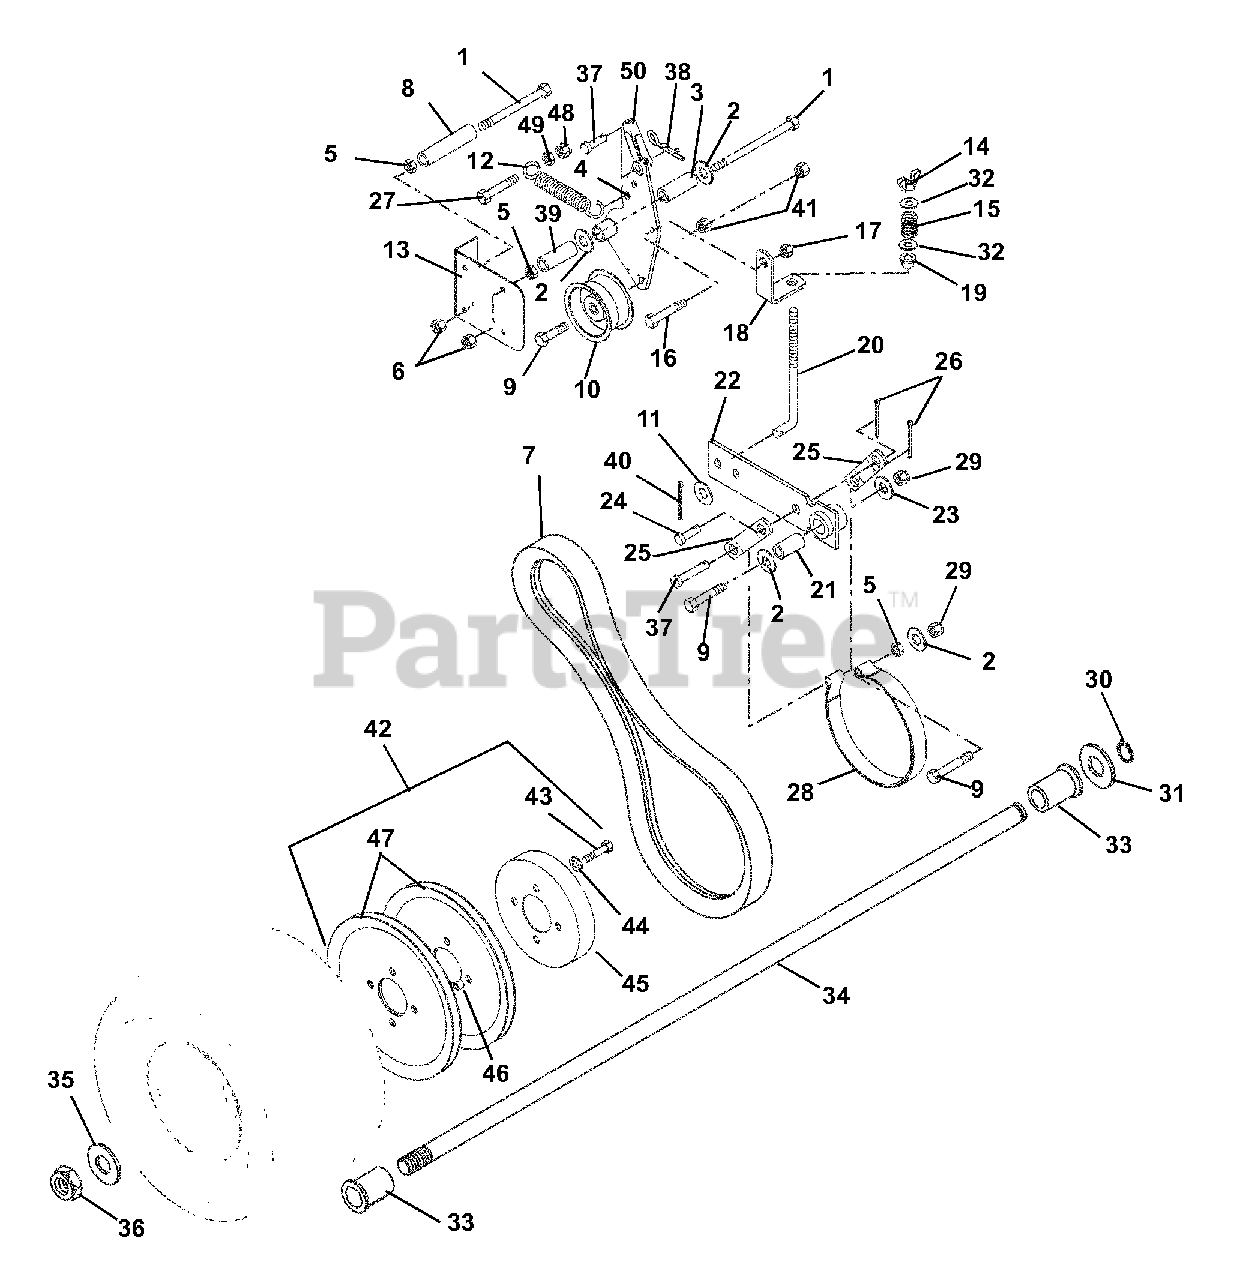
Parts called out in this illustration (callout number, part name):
1	@BLT-HEX .38-16X4.50 GR5 YWZC
2	@WSHR-FL-STL.406X.812X.065 YWZ
3	BUSH.,S.385X.610X1.80 ST
4	WMT - WHEEL CLUTCH ARM
5	@NUT-HEX .38-16 YWZC
6	@NUT-LK-TOP-FLG .38-16 YWZC
7	BELT, TRACTION DRIVE
7	BELT - TRACTION DRIVE - PRO
8	BSHG, SPACER, 3.25X3/8IDX5/8OD
9	@BLT-HEX .38-16X2.00 GR5 YWZC
10	IDLER 2.75X1.25
11	@WSHR-FL-STL.344X.688X.065YWZC
12	SG-TENS .105X1.00X5.0
13	KIT-BELT COVER W/DECALS
14	NUT-NYLK WING .312-18 YWZC
15	SG-COMP .125X.78X1.00 YWZ
16	@BLT-HEX .25-20X.75 GR5 YWZC
17	@NUT-LK-NYL .250-20 YWZC
18	BRACKET, BRAKE LINK
19	BSHG-FLG .320X.620X.312 NY
20	ROD, BRAKE
21	BUSH.,S.391X.622X.950 ST
22	WLDMT,BRAKE ARM
23	WSHR-FL-STL .406X1.00X.188 YWZ
24	PIN-CLEV .38X.75 YWZC
25	LINK,BRAKE ARM
26	@PIN-CTR .12X.75 EXTPRSQCT YWZ
27	@BLT-HEX .31-18X2.00 GR5 YWZC
28	ASM, BRAKE BAND, PRO
29	@NUT-LK-NYL .38-16 YWZC
30	RG-RTNG-EXT .906X.078
31	WSHR-FL-STL 1.010X1.505X.062YZ
32	@WSHR-FL-STL.38X.875X.083 YWZC
33	BSHG-FLG 1.010X1.38X1.4X1.65
34	SHAFT, AXLE
35	@WSHR-FL-STL.812X1.50X.135YWZC
36	NUT-LK-JAM-NYL .75-10 YWZC
37	PIN-CLEV .38X1.25 YWZC
38	PIN-HAIR INT .08X.18X1.18 YWZC
39	BUSHING, SPACER .385X.561X1.38
40	@PIN-CTR .09X.75 EXTPRSQCT YWZ
41	@NUT-LK-CTR-JAM .375-16 YWZC
42	ASSY, PULLEY & DRUM
43	@BLT-HEX .31-18X1.50 GR5 YWZC
44	@WSHR-LK .31X.078 REG YWZC
45	DRUM,BRAKE
46	BUSH.,S.385X.625X.475 ST
47	SHEAVE 8"
48	@NUT-LK-CTR .31-18 YWZC
49	@NUT-HEX .31-18 YWZC
50	CLEVIS, .38-24 ADJ.
